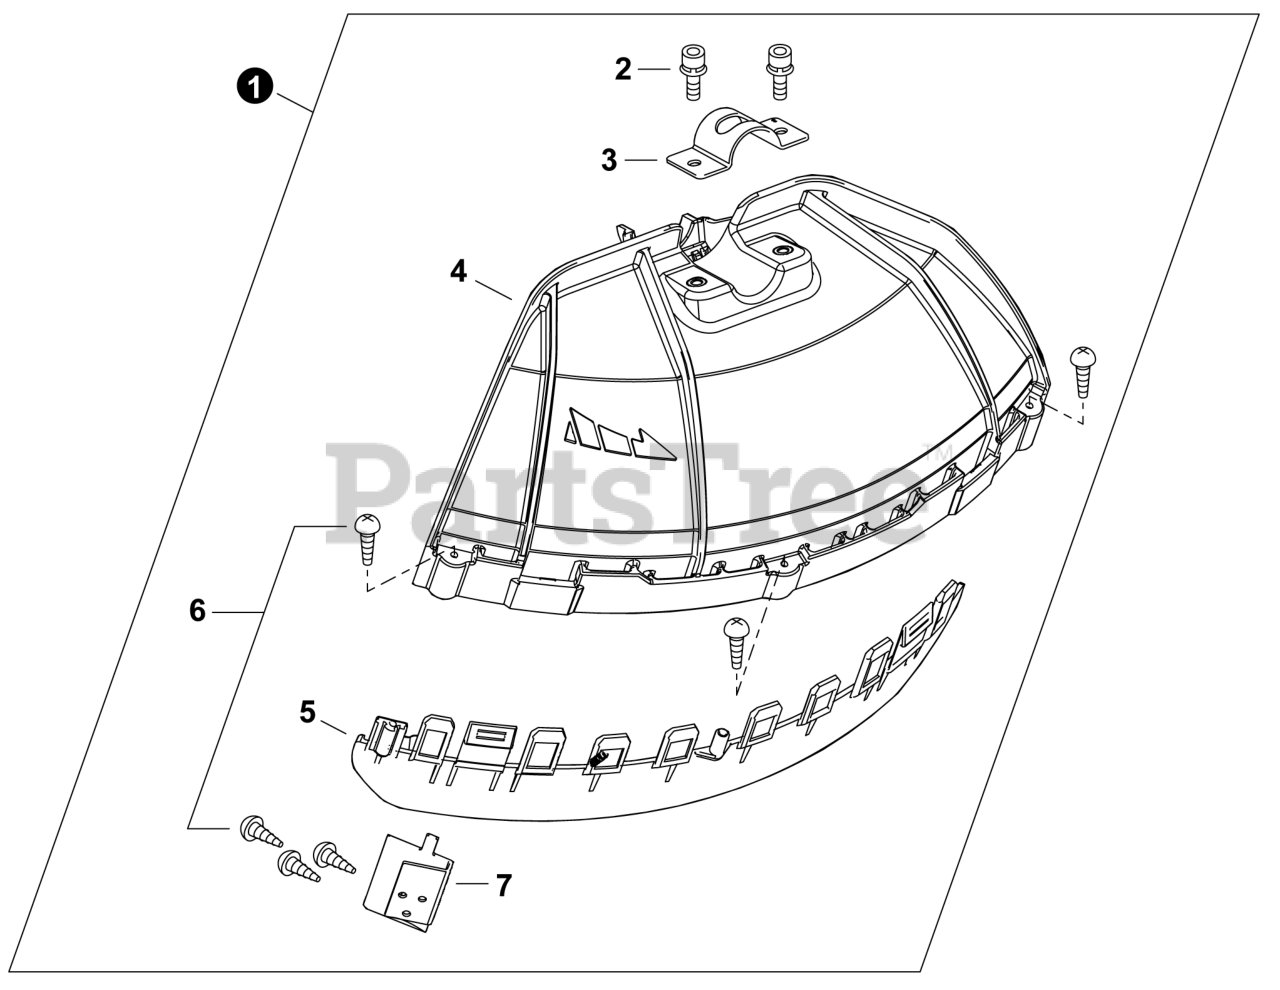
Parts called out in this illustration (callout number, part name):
1	DEBRIS SHIELD ASSY
2	BOLT 6x20
3	BRACKET, SHIELD
4	DEBRIS SHIELD - BLADE
5	DEBRIS SHIELD - TRIMMER EXTENSION
6	SCREW TAPPING
7	CUTTER, LINE
